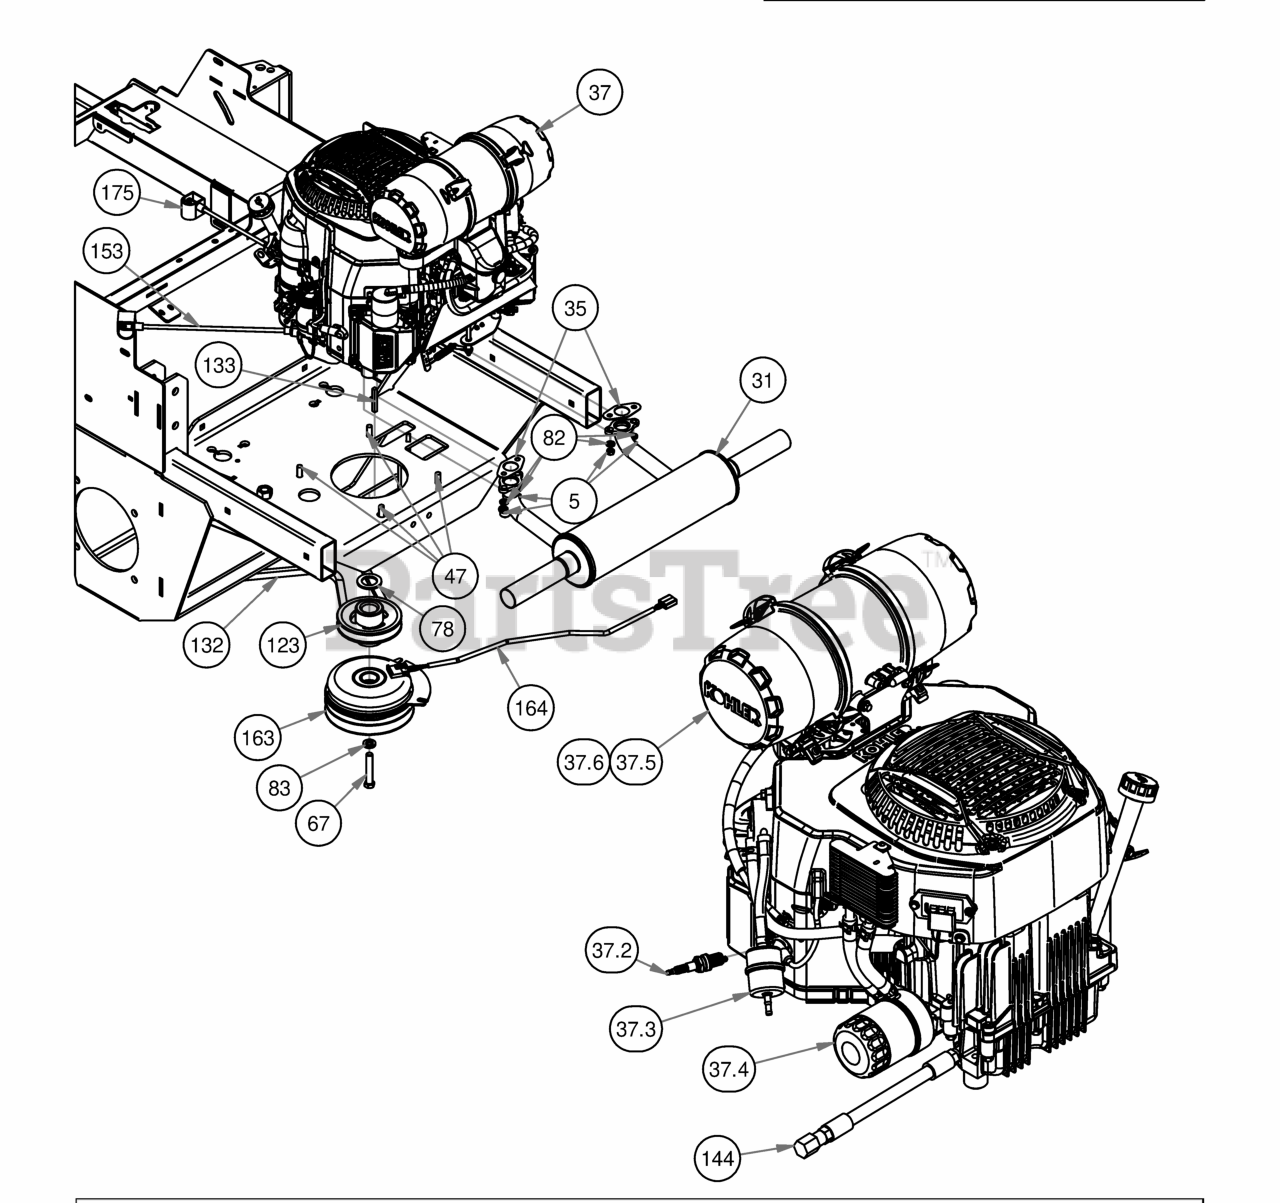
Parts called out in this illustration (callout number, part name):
5	M8-1.25 Zinc Nut
31	2019 Rebel Kohler CV752 Muffler
35	Exhaust Gasket
37	Kohler Command Engine
37.2	Spark Plug
37.3	25/26 HP Kohler Fuel Filter
37.4	Oil Filter
37.5	Canister Air Filter- Outer
37.6	Canister Air Filter- Inner
47	3/8 x 1 1/8 bolt
67	7/16" x 2 1/2" Hex Bolt
78	1 1/8" Flat Spacer
82	5/16" Lock Washer
83	7/16" Lock Washer
123	4 3/4 Motor Pulley
132	2019 Rebel Pump Belt
133	1/4 x 2 Square key Stock
144	Oil drain Hose for Yamaha
153	14" Red Battery Cable-Base Outlaw
163	Clutch Assembly
164	Clutch Pigtail
165	2019 Rigid Frame
175	Starter Cable
